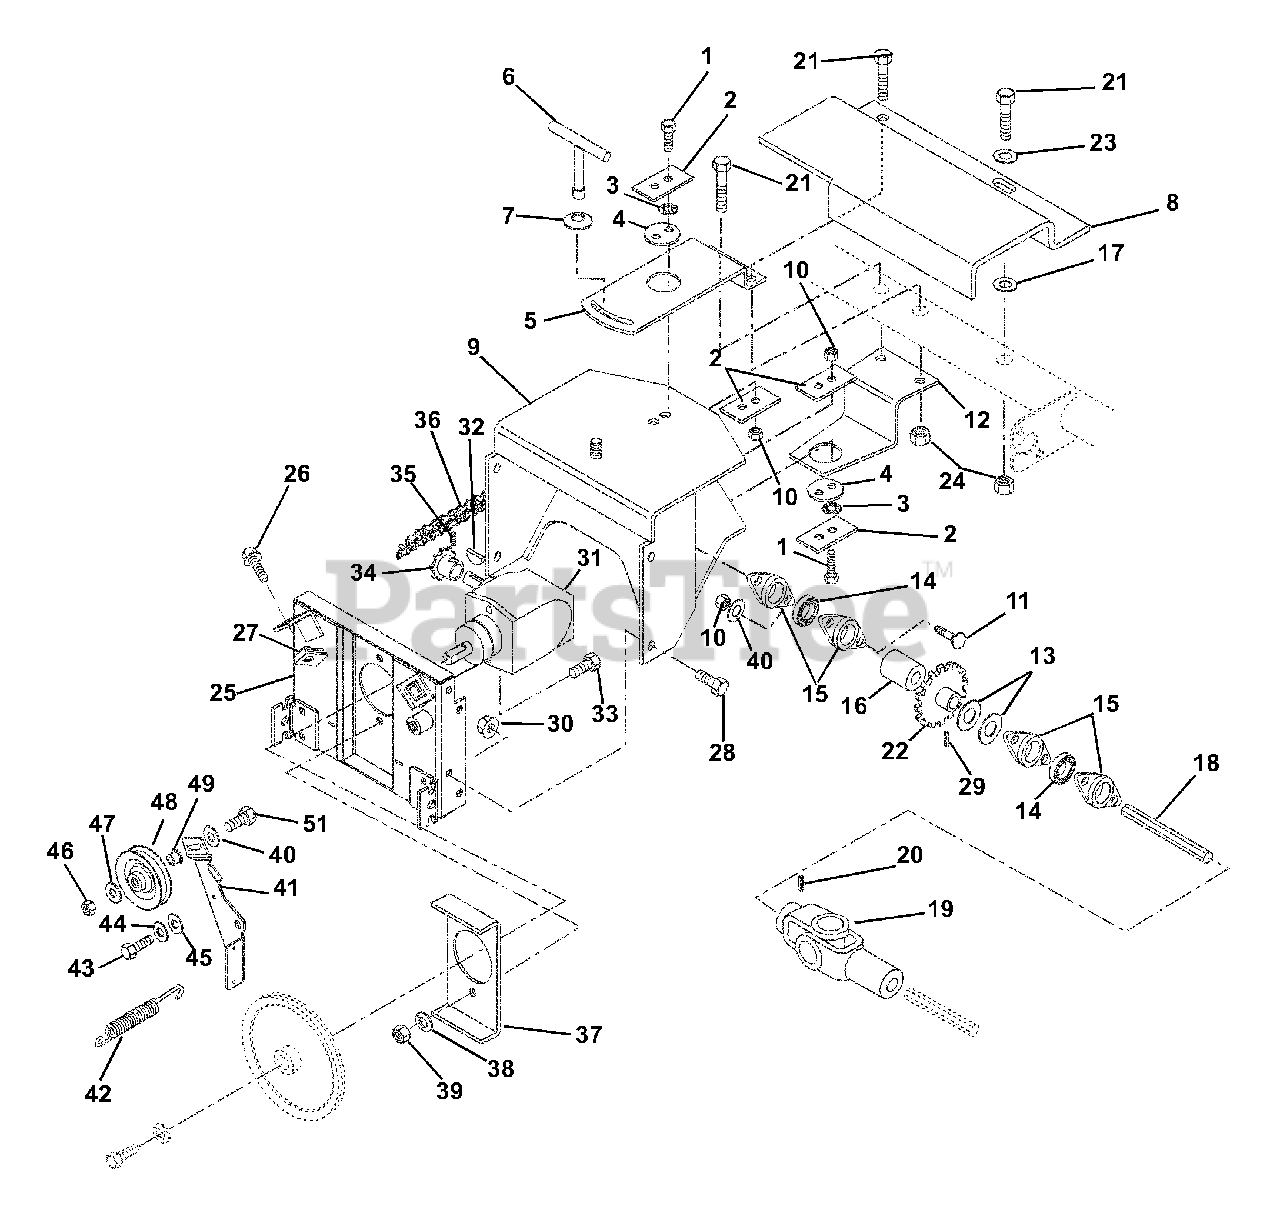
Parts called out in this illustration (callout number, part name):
1	Bolt, Hex .31-18 x 1.25 Grade 5
2	Retainer
3	Washer, Locking Internal .313 x .030
4	Pivot, Center
5	Plate, Top Mount
6	T-Lock Handle
7	Washer, Cupped Serrated .38
8	Guard, Shaft
9	Frame, Adapter
10	Nut, Locking Top .31-18
11	Bolt, Round Head Square Neck .31-18 x .75 Grade 5
12	Plate, Bottom Mount
13	Washer, Flat Steel 1.015 x 1.500 x .125
14	Bearing, Ball
15	Flange, Bearing
16	Spacer 1.006 x 1.307 x .500
17	Washer, Flat Steel .390 x .88 x .18
19	Universal Joint
20	Pin, Roll .188 x 1.50
21	Bolt, Hex .38-16 x 3.25 Grade 5
22	Sprocket
23	Washer, Flat Steel .406 x .812 x .065
24	Nut, Locking Center .38-16
25	Plate, Mounting Broom
26	Bolt, Hex Flanged Whizloc Head .38-16 x .75
27	Nut, Retainer .38-16
28	Bolt, Hex .38-16 x .75 Grade 5
29	Pin, Roll .188 x 1.75
30	Nut, Locking Center .38-16
31	Gear Box Assembly
32	Key, Woodruff .188 x .75 x .313 SAE 9
33	Bolt, Hex .38-16 x 1.25 Grade 5
34	Sprocket
35	Screw, Set .25-20 x .25 Socket Head Cup Point
37	Plate, Stiffener
38	Washer, Lock .38 x .094
39	Nut, Hex .38-16
40	Washer, Flat Steel .38 x .875 x .083
41	Arm, Auger/Brake-High with Lining
42	Spring, Tension .06 x .492 x 5.25
43	Bolt, Hex .31-18 x .75 Grade 5
44	Washer, Locking .312 x .097 Heavy
45	Washer, Flat Steel .328 x 1.00 x .094
46	Nut, Locking Top Flange .31-18
47	Washer, Flat Steel .344 x .688 x .065
48	Idler
49	Spacer, Bearing
50	Washer, Flat Steel .38 x .875 x .083
51	Bolt, Hex .31-18 x 1.25 Grade 5
